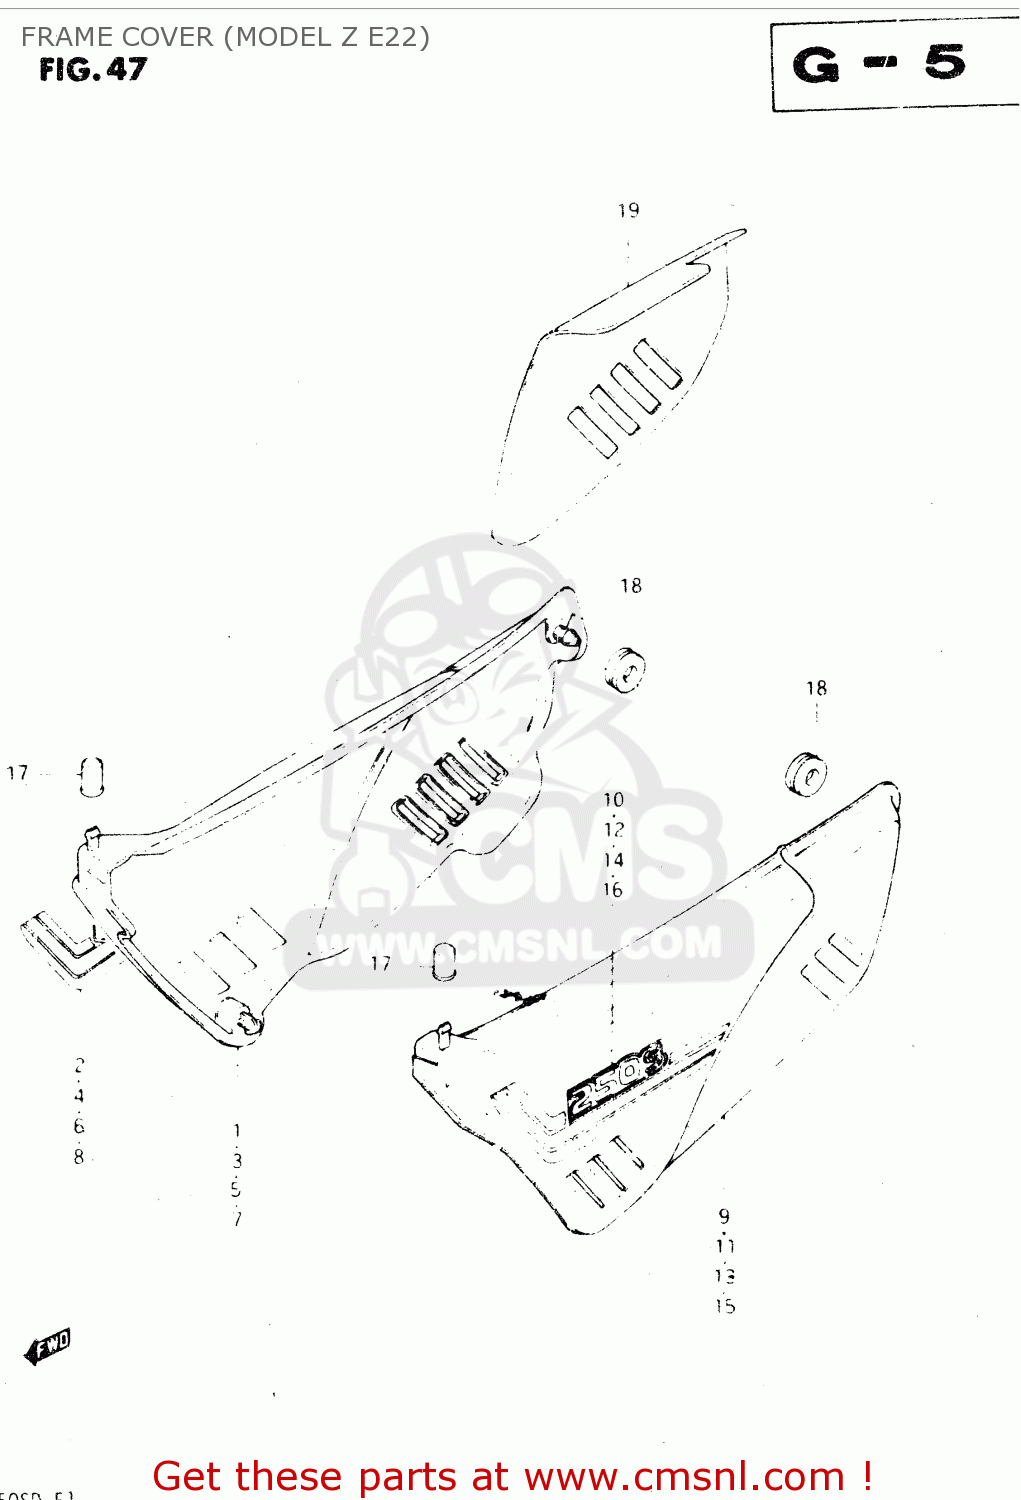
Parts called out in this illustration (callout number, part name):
1	COVER, FRAME RH (BLACK)
2	TAPE, RH
3	COVER, FRAME RH (BLUE)
4	TAPE, RH
5	COVER, FRAME RH (YELLOW)
6	TAPE, RH
7	COVER, FRAME RH (RED)
8	TAPE, RH
9	COVER, FRAME LH (BLACK)
10	TAPE, LH
11	COVER, FRAME LH (BLUE)
12	TAPE, LH
13	COVER, FRAME LH(YELLOW)
14	TAPE, LH
15	COVER, FRAME LH (RED)
16	TAPE, LH
17	CUSHION
18	CUSHION
19	HEAT SHIELD,FRAME COVER
